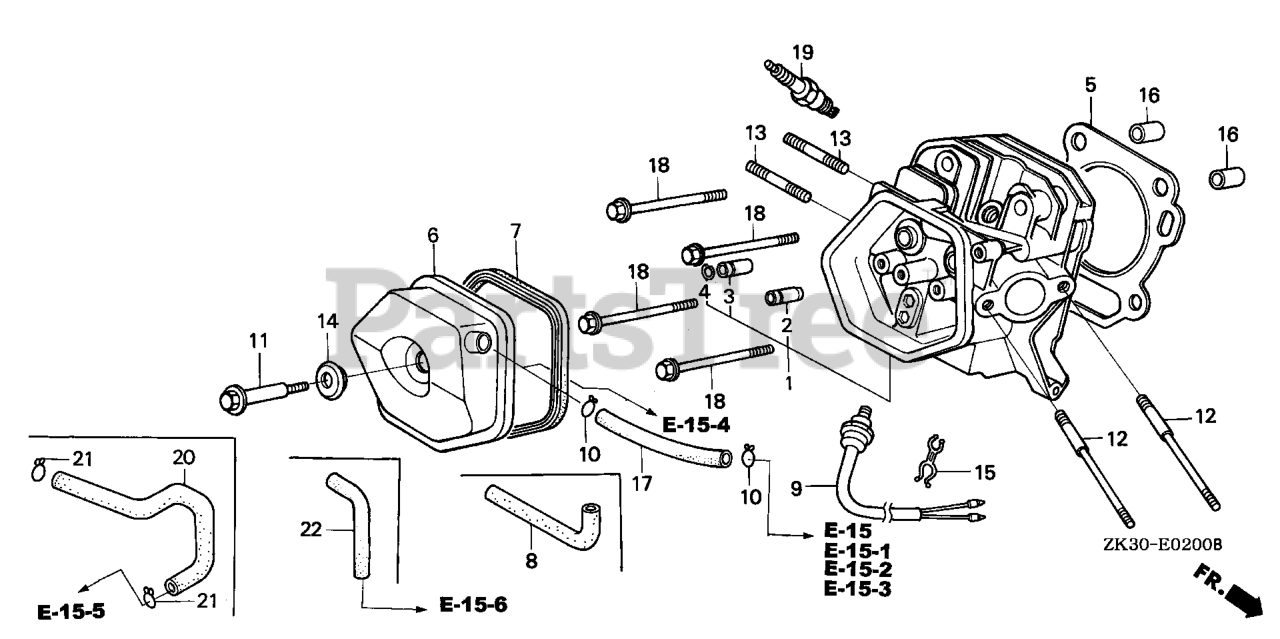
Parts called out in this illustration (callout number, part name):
1	CYLINDER HEAD
2	GUIDE, VALVE (OS)
4	CLIP, VALVE GUIDE
5	GASKET, CYLINDER HEAD
6	COVER, HEAD
7	GASKET, CYLINDER HEAD COVER
11	BOLT, HEAD COVER
12	BOLT, STUD (8X131.5)
13	BOLT, STUD
13	BOLT 2, STUD (8X32)
14	WASHER, HEAD COVER
16	PIN A, DOWEL (12X20)
17	BULK HOSE, VACUUM (11X1000) (Honda Code 4537312). (11X105)
18	BOLT, FLANGE (10X80)
19	SPARK PLUG (BPR5ES) (NGK)
19	SPARK PLUG (W16EPR-U) (DENSO)
19	SPARK PLUG (BPR6ES) (NGK)
19	SPARK PLUG (W20EPR-U) (DENSO)
